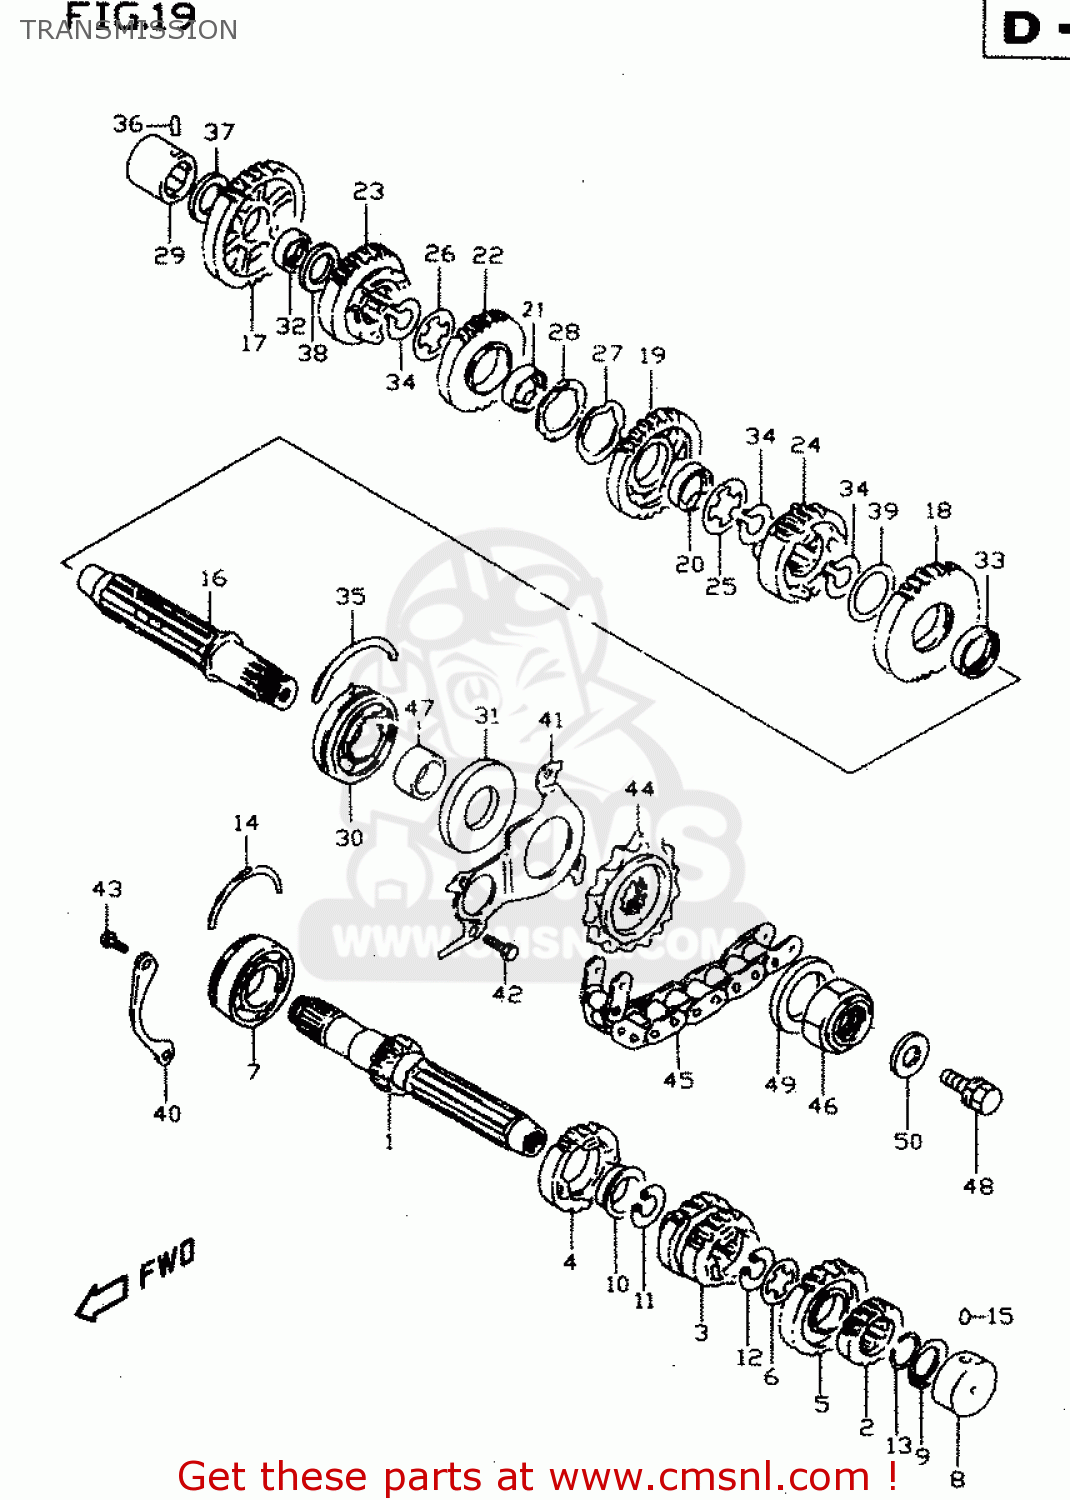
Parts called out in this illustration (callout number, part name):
1	SHAFT,COUNTER(NT:12)
2	GEAR,2ND DRIVE(NT:16)
3	GEAR,3RD & 4TH DRIVE(NT:17/20)
4	GEAR,5TH DRIVE(NT:22)
5	GEAR,6TH DRIVE(NT:21)
6	WASHER,LOCK
7	BEARING(25X62X17)
8	BEARING(20X34X17.5)
9	SEAL,OIL(20X31.2X2.7)
10	BUSHING
11	RING,SNAP
12	RING,SNAP
13	CIRCLIP
14	C RING
15	PIN
16	SHAFT,DRIVE
17	GEAR,1ST DRIVEN(NT:37)
18	GEAR,2ND DRIVEN(NT:33)
19	GEAR,3RD DRIVEN(NT:28)
20	BUSH
21	BUSH
22	GEAR,4TH DRIVEN(NT:28)
23	GEAR,5TH DRIVEN(NT:27)
24	GEAR,6TH DRIVEN(NT:23)
25	WASHER,LOCK
26	WASHER,LOCK
27	WASHER,LOCK
28	WASHER
29	BEARING(20X34X20)
30	BEARING(25X62X21.6)
31	SEAL,OIL(34X62X6)
32	BUSH(22X26X9)
33	BUSH(28X32X9.5)
34	CIRCLIP
35	C RING
36	PIN
37	SHIM(20X34X1)
38	SHIM(22X34X1)
39	SHIM(28X38X1)
40	RETAINER,CNTR SHAFT BEARING
41	RETAINER,DRIVE SHAFT OIL SEAL
42	BOLT
43	SCREW ,6X16
44	SPROCKET,ENGINE(NT:15)
45	CHAIN,DRIVE(112LE)
46	NUT
47	SPACER(25X34X17.5)
48	BOLT
49	SHIM(25X40X1.5)
50	WASHER
